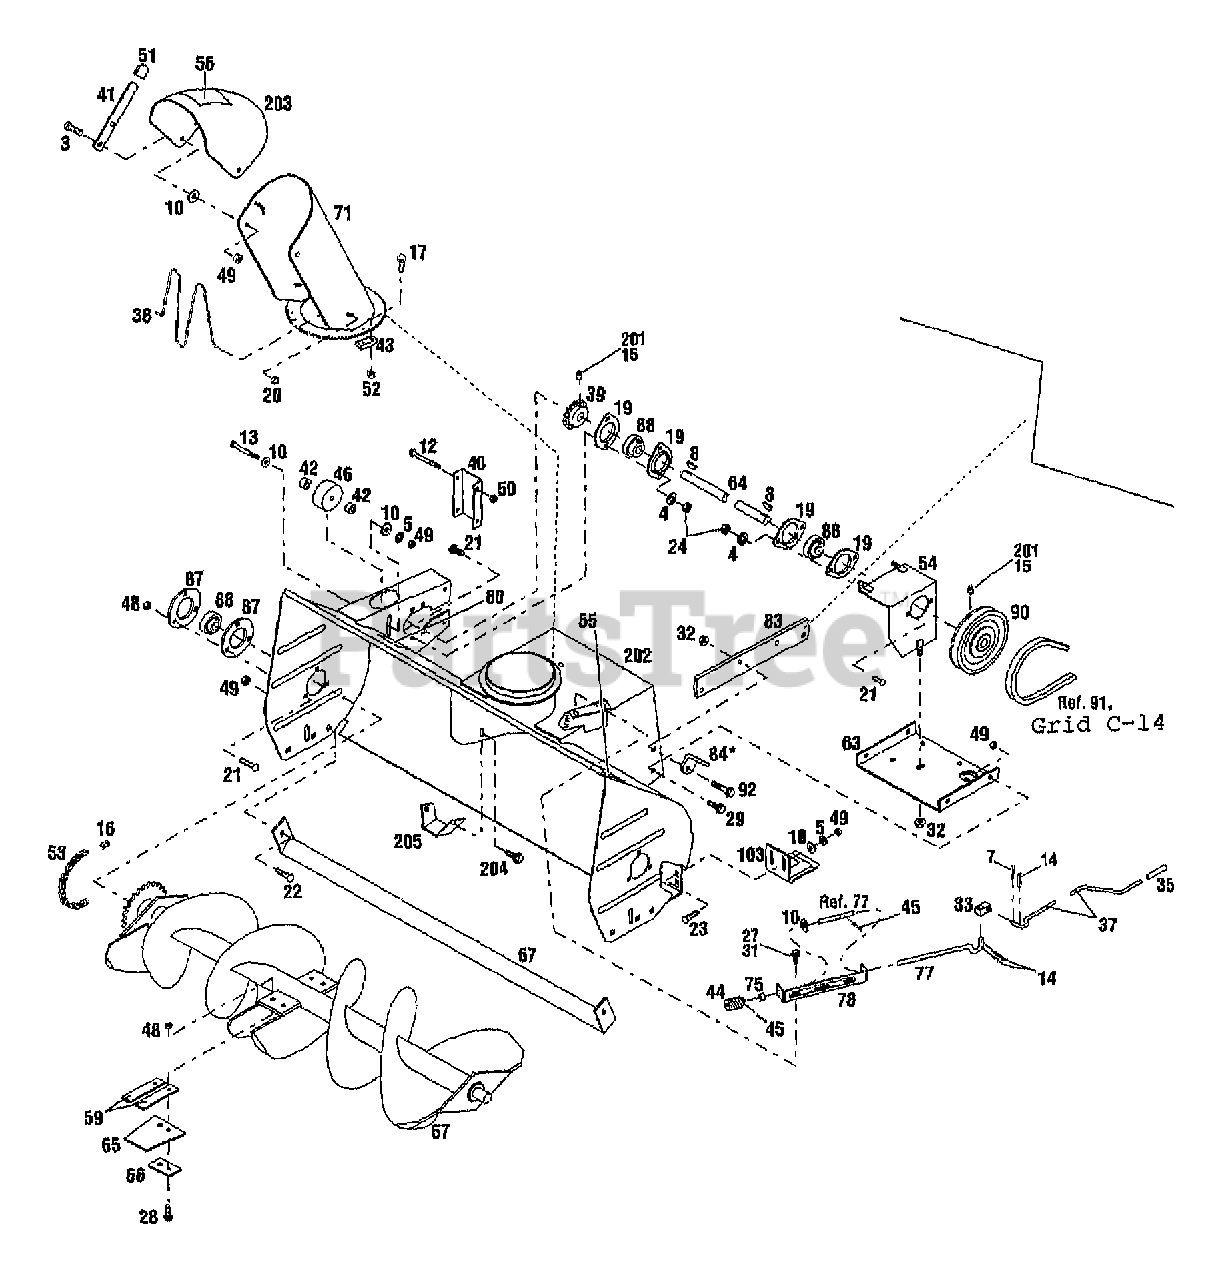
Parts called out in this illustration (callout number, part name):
3	SCR-HH 3/8-16X.75 G5 ZP
4	WASHER-LK .312 ZP
5	WASHER-LK .375 @ DEPL
7	PIN-COTTER .125 X .75 ZP
8	KEY-WOODRUFF .188X.75
10	WASHER-FLAT 3/8 SAE
12	SCR-HH 1/4-20X3.0 G5 ZP
13	SCR-HH 3/8-16X3.0 G5 ZP
14	PIN-ROLL 1/8 X 3/4
15	SCR-SET
16	LINK-CONNECTOR
17	SCR-SEMS MACH
19	BEARING-FLANGE
20	NUT-PUSH 3/16
21	SCR-CARR 5/16-18X.75 G2 ZP
22	BOLT-3/8-16 X 3/4
23	SCR-CARR 3/8-16X1.00
24	NUT-HEX 5/16-18 ZP
27	SCR-HFLK 5/16-18X.75 ZP
28	SCR-HFLK 5/16-18X1.25 ZP
31	NUT-HFLK 5/16-18 ZP
32	NUT-HFLK 3/8-16 ZP
33	BLOCK-SWIVEL NYLON
35	GRIP-PLASTIC
37	CRANK-HANDLE
38	GUARD-CHUTE
40	COVER-END
41	LEVER-ADJUSTING
42	SPACER-.68X.39X.46
43	CLIP-HOLD DOWN
44	GEAR-WORM LH
45	PIN-DRIVE .09X.75
46	BLOCK-TENSION
48	NUT-TOP/LK 5/16-18 ZP
49	NUT-LOCK 3/8-16
50	NUT-LOCK 3/8-16
51	GRIP-VACUCUT
52	NUT-H/LK M10-24 NYLOCK
53	CHAIN-DRIVE
55	DECAL-WARNING
56	DECAL-WARNING
57	ASSY ROTOR 38"
59	SLINGER EXTENSION
60	DECAL-WARNING
63	ASSM-PLATE
64	SHAFT-ROTOR DRIVE
67	SCRAPER
71	CHUTE-DISCHARGE
75	SPACER-PINION
77	SHAFT-PINION
78	SUPPORT-SHAFT
83	ARM-LIFT
84	BRACKET-SPRING
88	BEARING-BALL
90	SHEAVE-DRIVE
92	SCR-HFLK 3/8-16X1.25 ZP
103	SHOE-SKID
201	LOCTITE-242 (.5 ML TUBE)
202	ASSM-HOUSING W/DECALS
203	ASSM-DISCHARGE CAP
204	SCR-HH 3/8-16X.50
205	ASSM-DEFLECTOR
